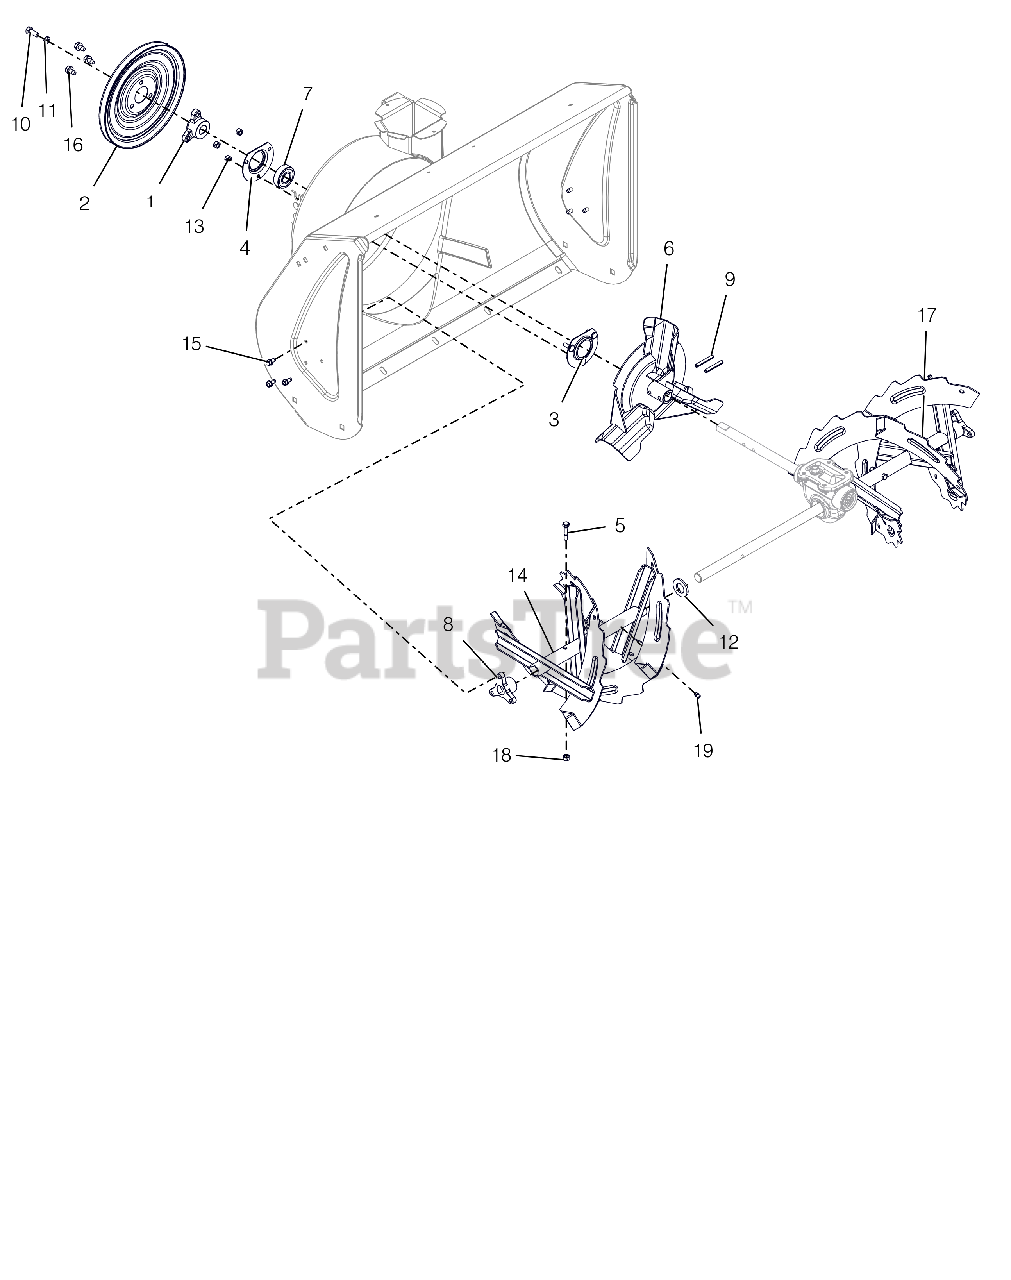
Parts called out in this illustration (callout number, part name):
1	PULLEY HUB, BOLT-ON D-BORE .75
2	PULLEY,SPIN FORM SINGLE GROOVE
3	BEARING FLANGE
4	BEARING FLANGE
5	SHEAR BOLT
6	IMPELLER, COMPACT 12" 3-BLADE
7	BRG-BALL .750X1.750X.50
8	BUSHING, RAKE SHAFT .75"
9	PIN-ROLL .250X1.75
10	BLT-HEX .31-24X.75 YWZC GR5
11	WSHR-LK .312X.097 HVY YWZC
12	@WSHR-FL-STL.812X1.50X.135YWZC
13	@NUT-LK-CTR .25-20 YWZC
14	RAKE, 28" RH, BLK SERR W/ZERK
15	SCR-TAP .25-20X.50 HWH TR YWZ
16	@SCR-TAP .31-18X.50 HWH TR YWZ
17	RAKE, 28" LH, BLK SERR W/ZERK
18	@NUT-LK-CTR .25-20 YWZC
19	ZERK,FITTING .25X.125 DRIVE IN
